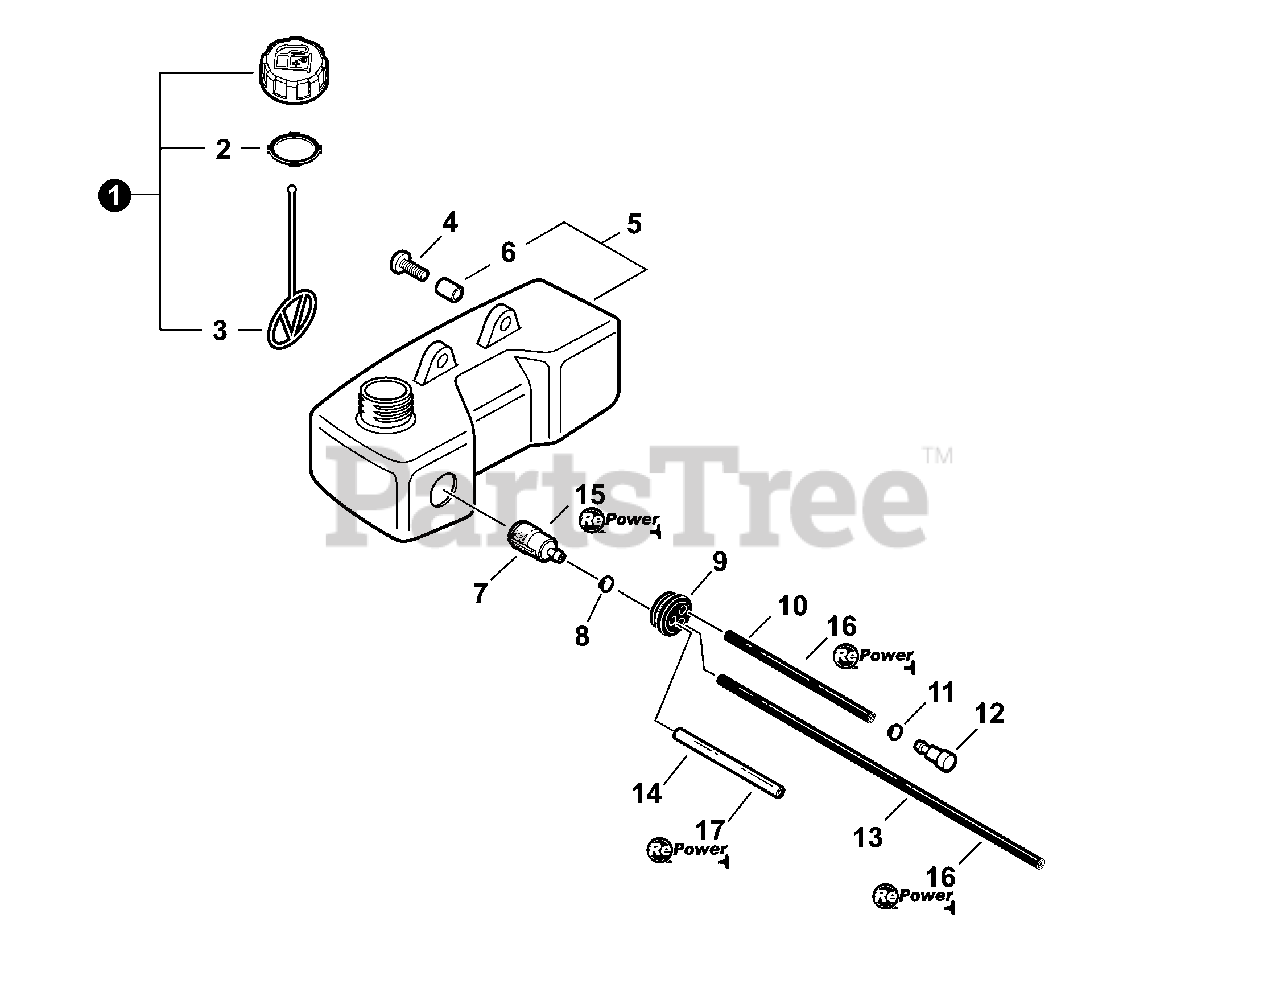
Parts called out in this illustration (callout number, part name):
1	CAP ASSY, FUEL
2	GASKET, FUEL CAP
3	CONNECTOR, CAP L= 100mm
4	SCREW 5×15
5	TANK ASSY, FUEL
6	SPACER 6.2×7.8×6
7	FILTER, FUEL
8	CLIP 6MM
9	GROMMET, FUEL 5
10	PIPE, FUEL 3×5×70 BLACK
11	CLIP 5.5
12	VENT ASSY
13	PIPE, FUEL 3×5×210
14	PIPE, FUEL 3×6×50
15	TUNE-UP KIT - REPOWER
16	PIPE, BULK - REPOWER 3×5mm BLACK
17	PIPE, BULK - REPOWER 3×6mm CLEAR
